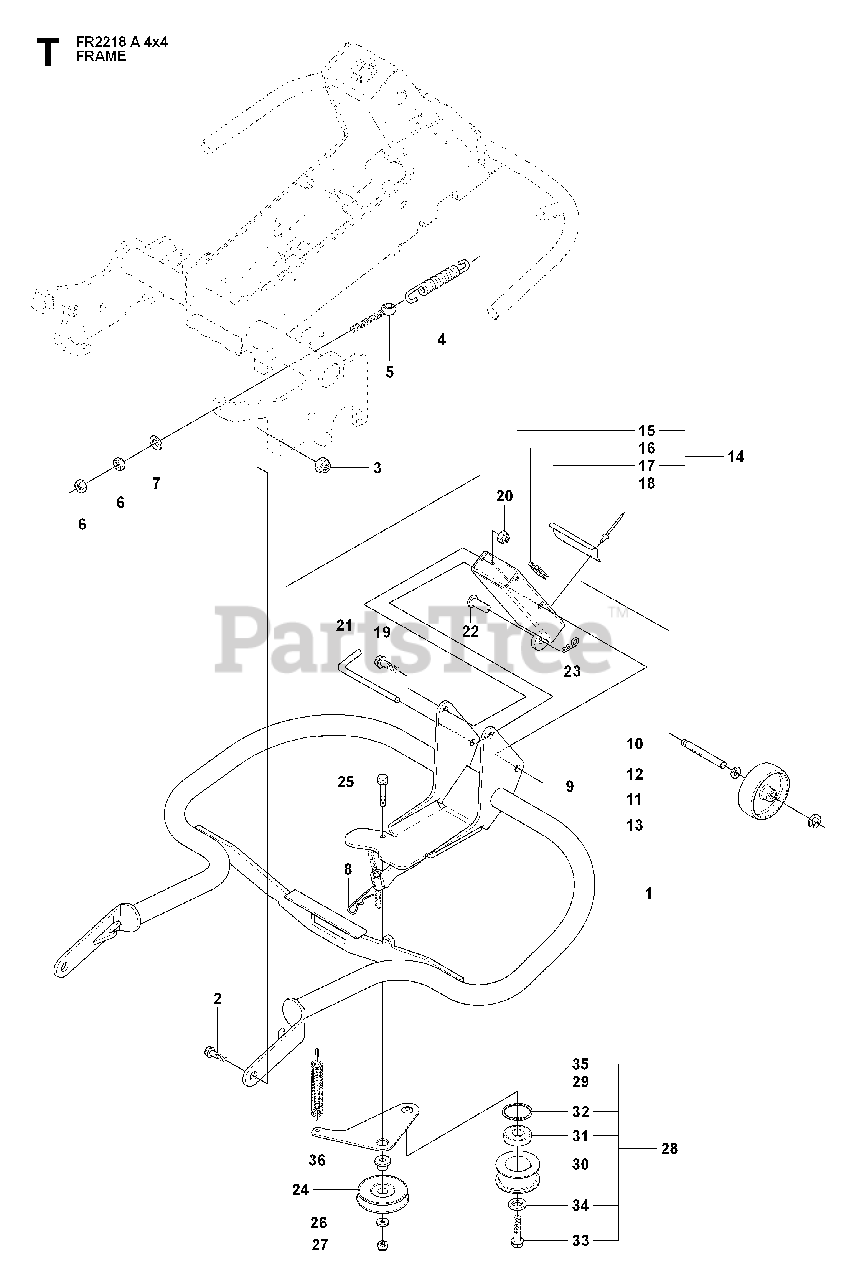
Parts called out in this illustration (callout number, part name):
6	NUT
7	WASHER
9	WHEEL ASSY
13	RETAINING RING
14	LINK ASSY
20	LOCKNUT M8
27	LOCKNUT M8
28	BELT TENSIONER ASSY
29	TENSIONER
30	%PULLEY
31	BALL BEARING 6004-2RS1
32	RETAINING RING
35	SPRING
